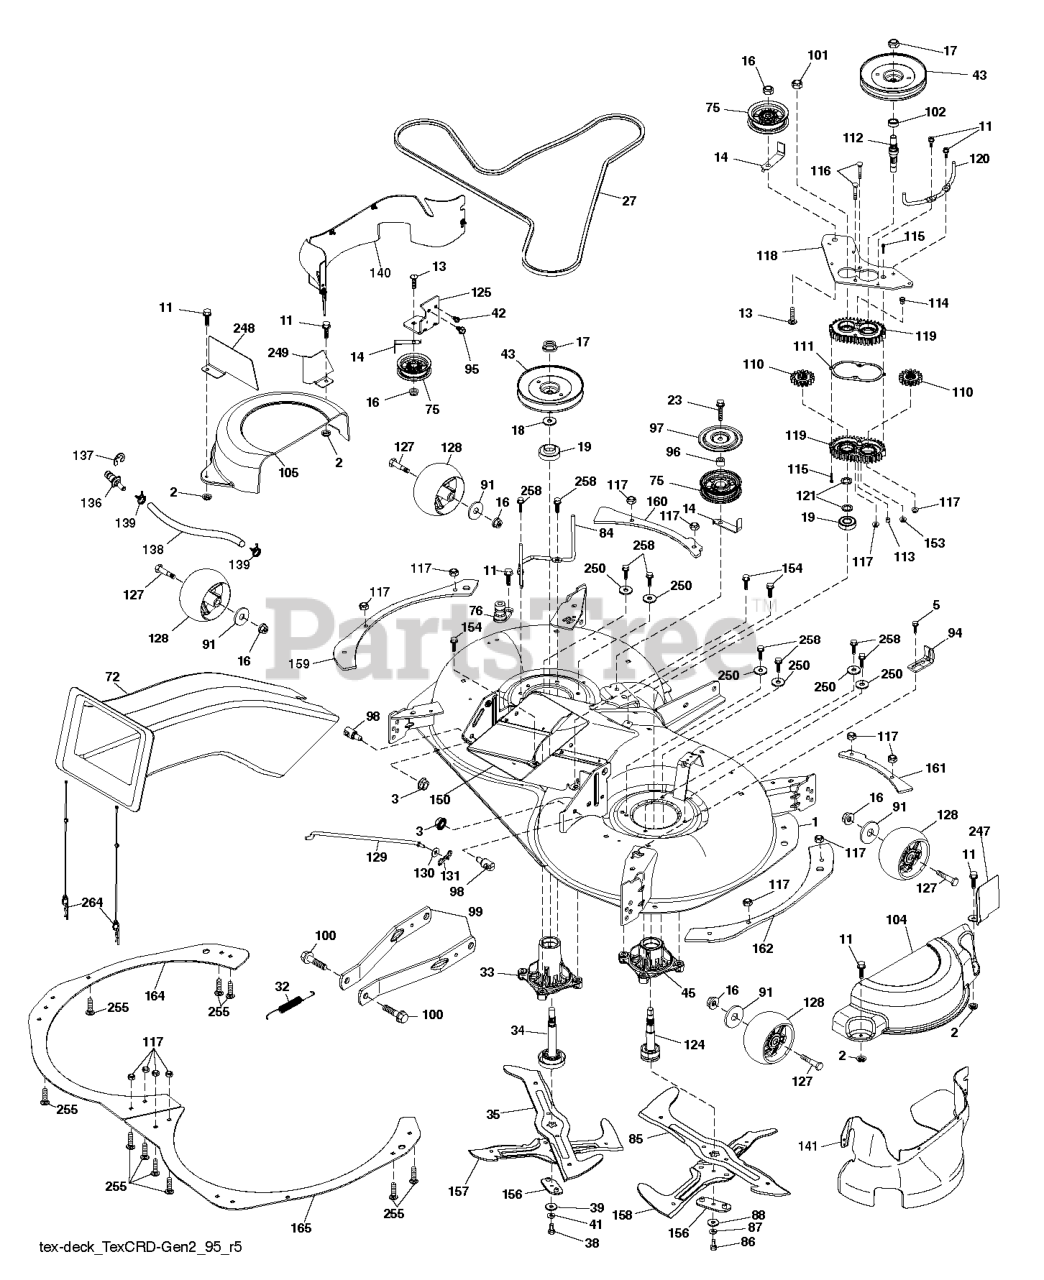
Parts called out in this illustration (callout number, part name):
1	DECK SVC 107HP.EZMUL.498
2	PALNUT 1/4
3	NUT LOCK HEX FLANGE 5/16-18
5	BOLT.5/16HEX.WHS.HD
11	SCREW.1/4-20X5/8
13	BOLT.3/8-16X1.50
14	KEEPER, BELT IDLER
16	NUT LOCK FLG 3/8-16 UNC
17	NUT.FLANGE.LOCK.TOP
18	WASHER.SPACER.MANDREL
19	BEARING.MANDREL.TOP.EXTENDED
23	SCREW LT
27	BELT.ELECT.MOWER.DRIVE 97.8 EL
32	SPRING 107CM & 97CM ELECTRIC D
33	RP.HOUSING.MANDREL.4PT.
34	SHAFT ASM.MNDRL.N/GREASEABLE
35	BLADE.3N1.LH.CRD
38	BOLT.BLADE.7/16-20 X 1.5 GR8
39	WASHER.7/16.FLAT
41	WASHER 7/16 LOCK
42	SCREW
43	PULLEY PULLEY MANDREL 5.438 PD
45	HOUSING.MANDREL.44/46" VENT
72	CHUTE.SLOTTED.HOLES.TEX.CRD.II
75	FLAT IDLER PULLEY
76	1/2" BARB.DECK.WASHOUT.PORT
84	KEEPER KEEPER. LH MANDREL BELT
85	BLADE.3N1.RH.CRD
86	BOLT.3/8-24X1.25GR8. LHTHRD
87	SLW 3/8 STD
88	WASHER.BLADE
91	WASHER
94	BRKT.CLUTCH.CABLE
95	SCREW, 3/8-16X3/4
96	SPACER
97	PROTECTOR
98	STUD.FASTNER.W/ANTI-ROTATE
99	ARM.SUSPENSION.MOWER.R
100	BOLT.SHOULDER
101	NUT.CROWNLOCK.9/16 -18.UNC
102	SPACER BEARING
104	COVER.MANDREL.107.RH.GEN.2
105	COVER.MANDREL.107.LH.GEN.2
110	CRD.SPUR.GEAR
111	GASKET GASKET GEARCASE
112	SHAFT SHAFT. CRD GEARCASE ADAP
113	PLUG PLUG OIL
114	VENT.BREATHER.1/8 NPT
115	SCREW
116	BOLT.CARIGE.SS.1/4-20X1.75GR5
117	NUT T
118	ARM ARM. CLUTCHING 107 TEX CRD
119	GEARCASE GEARCASE SUBASM
120	KEEPER KEEPER. RH MANDREL BELT
121	WASHER WASHER
124	MANDREL SHAFT NON/GREASE
125	BRACKET BRACKET IDLER CHASSES
127	BOLT.SHOULDER.3/8-16X3-5/8.
128	WHEEL.GAUGE.RALLY
129	ROD ROD. SWAY CRD GEN II
130	WASHER
131	PIN.COTTER.5/16.BOW TI
136	PLUG WASHOUT PORT HOOKUP
138	107.WASHOUT.PORT.HOSE (2 2)
139	HOSE.3/8.CLAMP (2 2)
140	GUARD.ASSEMBLY.107.LH.FRENCH
141	GUARD.ASSEMBLY.107.RH.FRENCH
150	CHUTE LOWER.WLDT.107.CRDII
153	NUT HEXAGON 9/16-18 G2 ZPB LOC
154	SCREW T-30 1/4-20 X
156	ADAPTER ADAPTER.CROSSBLADE.107
157	BLADE 107CM.CROSS.BLADE
158	BLADE.CROSS.RH.CRD.107
159	REINFORCE.PLATE.LH.FT.X431
160	REINFORCE.PLATE.LHS.BOLT.431
161	REINFORCE.PLATE.RH.FRT.X431
162	REINFORCE.PLAT.RH.SD.BLT.X431
164	BAFFLE.PLATE.PNT.107CRD.LT.BLK
165	BAFFLE.PNT.107.CRD.PLATE.RT.BK
247	GUARD BELT.CRD.RH.ISO X431 BLA
248	GUARD.STEEL.CRD.MANDREL.COV.FR
249	GUARD.STEEL.CRD.MANDREL.COV.FR
255	RHSNB, 1/4-20 X 1, GR5
258	BOLT.HEX.WASHR.HED.313-18X1.19
264	RETAINER.ASM.UPPERCHUTE.CRD2.5
